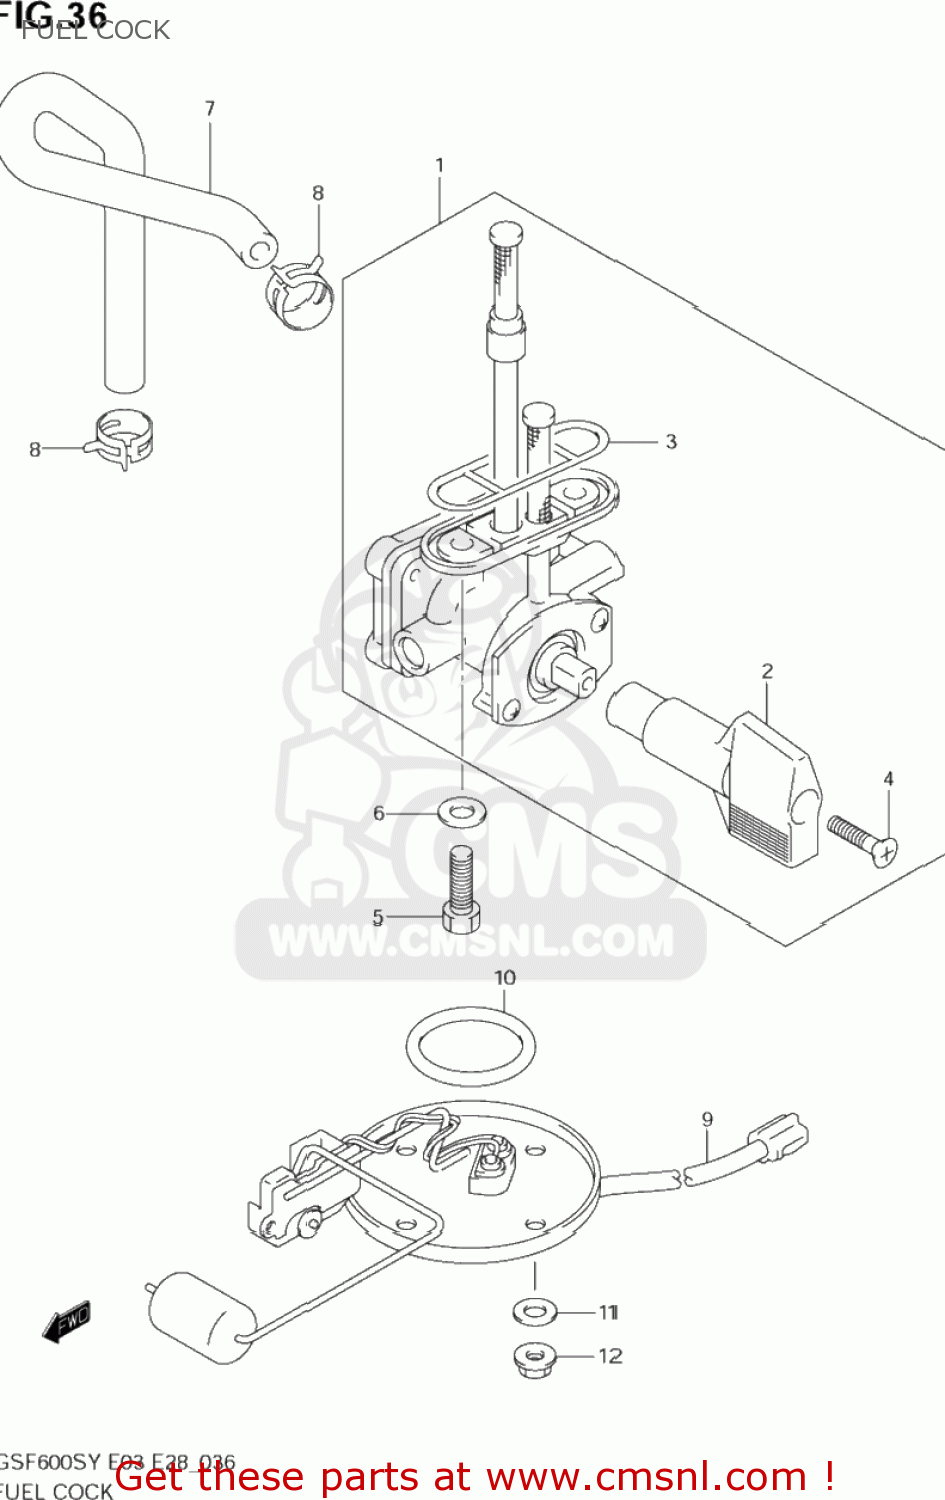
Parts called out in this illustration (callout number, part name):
1	COCK ASSY,FUEL
2	LEVER,FUEL COCK
3	GASKET,JOINT (NAS)
4	SCREW
5	BOLT(6X20)
6	GASKET(6.4X11.5X0.8) (NAS)
7	HOSE(7X12X600)
8	CLIP
9	GAUGE ASSY,FUEL LEVEL
10	O RING
11	WASHER(6.5X15X1.6)
12	NUT
